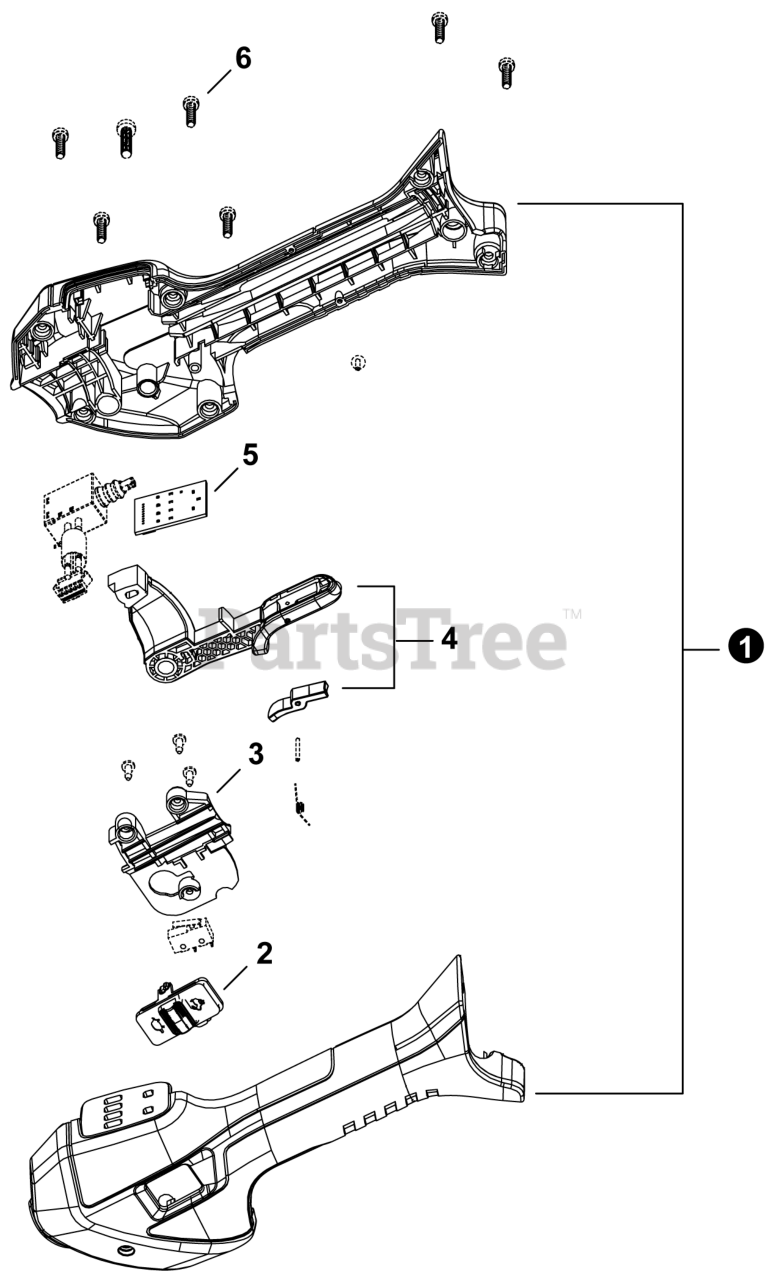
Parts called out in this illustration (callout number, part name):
1	HANDLE, CONTROL - SET
2	SWITCH, SPEED CONTROL
3	PLATE, MOUNTING
4	LEVER ASSY., THROTTLE
5	DISPLAY, LED
